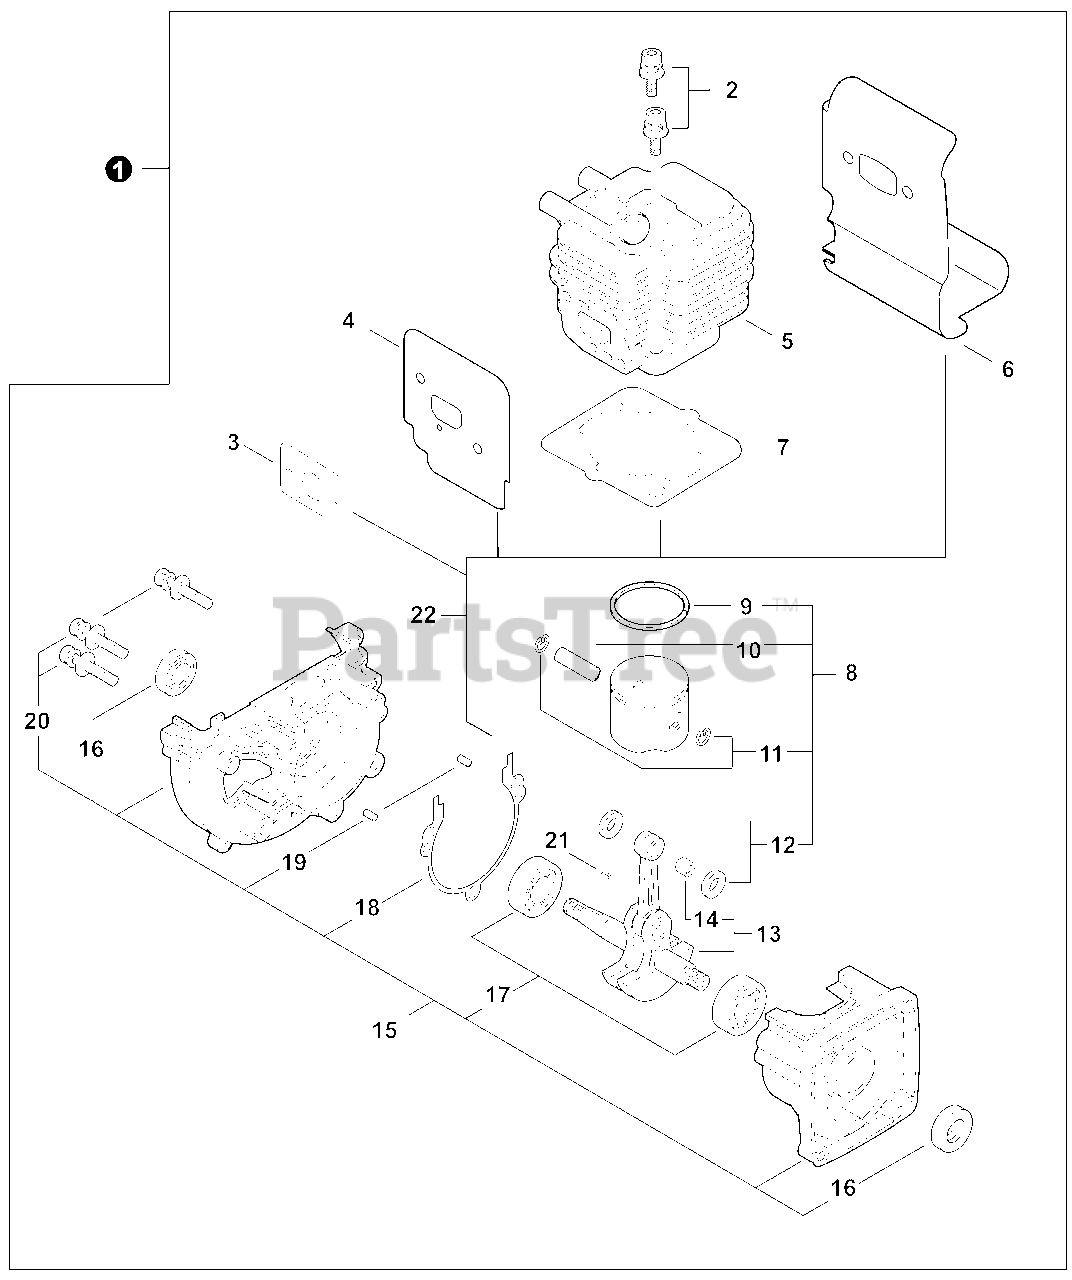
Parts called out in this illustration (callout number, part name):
1	SHORT BLOCK
2	BOLT 5×22
3	GASKET, INTAKE
4	HEAT SHIELD, INTAKE
5	CYLINDER
6	HEAT SHIELD, EXHAUST
7	GASKET, CYLINDER
8	PISTON KIT
9	RING, PISTON
10	PIN, PISTON 8
11	RING, RETAINING
12	WASHER, THRUST
13	CRANKSHAFT ASSY
14	BEARING, NEEDLE 8
15	CRANKCASE KIT
16	SEAL, OIL 12
17	BEARING, BALL
18	GASKET, CRANKCASE
19	PIN, LOCATING 4×8
20	BOLT 5×28
21	KEY, WOODRUFF
22	GASKET KIT: ENGINE, INTAKE, EXHAUST
